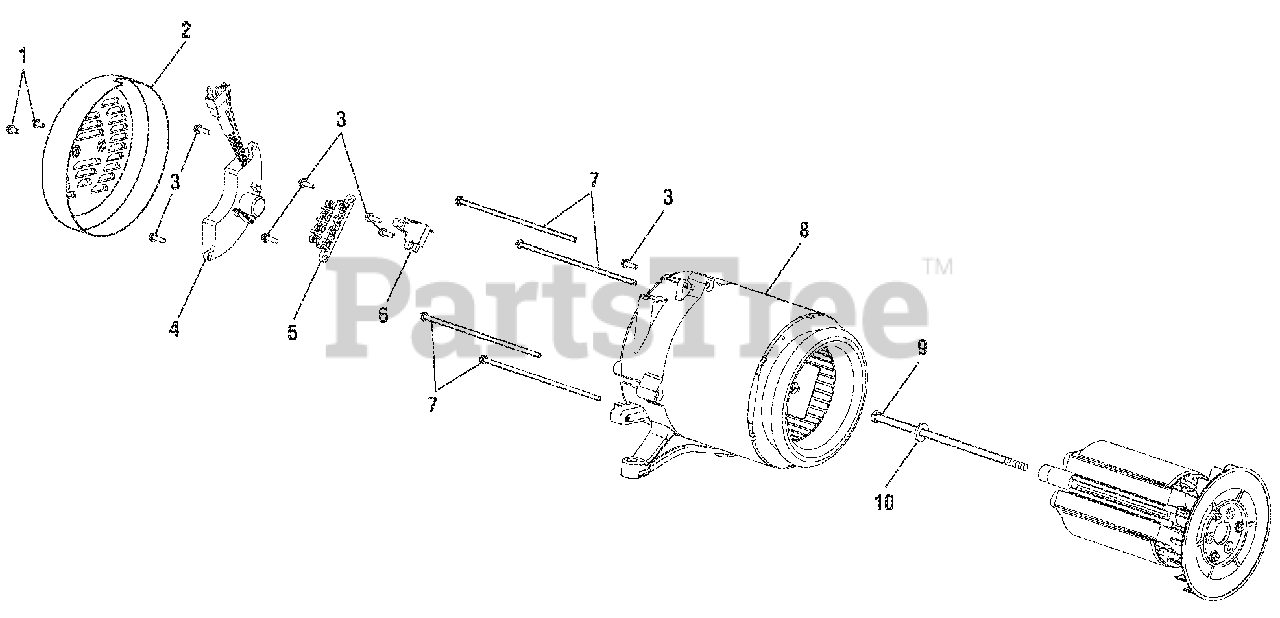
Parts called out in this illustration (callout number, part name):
1	Bolt (M5 x 10 mm, Hex Hd.)
2	Brush Cover
3	Bolt (M5 x 16 mm, Hex Hd.)
4	Automatic Voltage Regulator (5000 Watt)
5	Terminal Block Assembly
6	Brush Assembly Kit
7	Bolt (M6 x 187 mm, Hex Hd.)
8	Bearing Support
9	Bolt (Rotor)
10	Washer (5/16 in.)
